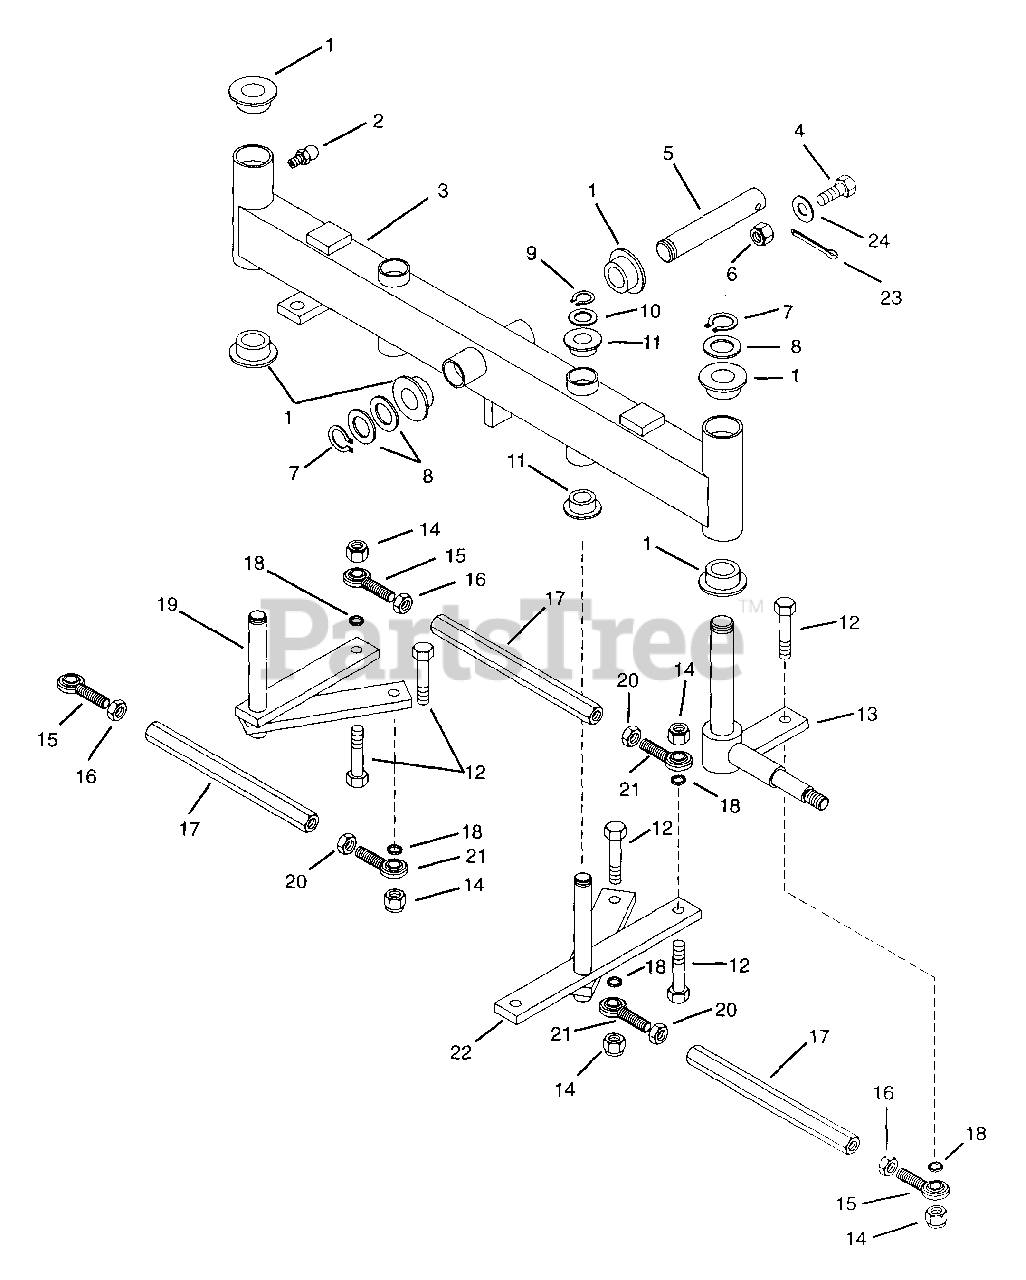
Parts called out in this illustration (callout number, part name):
1	Bushing-Flange 1.020 x 1.385 x .75 x 1.75
2	Fitting-Lube .25-28 x .256
3	Weldment, Axle
4	Bolt-Hex .38-16 x 1.00 Grade 5
5	Shaft, Pivot
6	Nut-Locking-Nylon .375-16 Grade 2
7	Ring-Retaining-External .906 x .078
8	Washer-Hardened-Thrust 1.002 x 1.552 x .030
9	Ring-Retaining-External .689 x .077
10	Bearing-Needle-Thrust .752 x 1.24 x .031
11	Bushing-Flange .762 x 1.0 x .580 x 1.48
12	Bolt-Hex .50-13 x 2.00 Grade 5
13	Weldment, Kingpin Left Hand
13	Weldment, Kingpin Right Hand
14	Nut-Locking-Nylon .50-13 Grade 5
15	Assembly, Rod End (Right Hand)
16	Nut-Jam .50-20 Grade 2
17	Rod, Tie
18	Spacer .520 x .625 x .125
19	Weldment, Steering Idler
20	Nut-Jam .50-20 Grade 2
21	Assembly, Rod End Left Hand
22	Weldment, Steering Arm
23	Pin-Cotter .250 x 2.00
24	Washer-Flat-Steel .281 x .620 x .065
